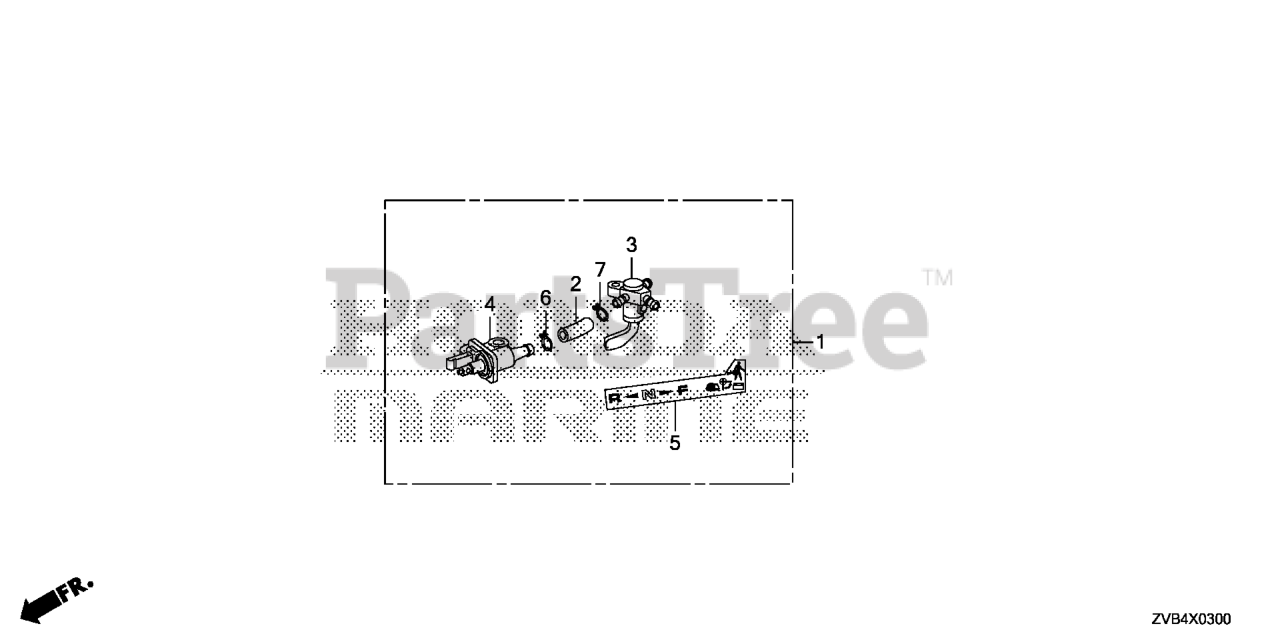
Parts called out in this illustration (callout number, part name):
1	CONNECTOR KIT, FUEL (US)
2	TUBE B, FUEL
3	PETCOCK ASSY. (THREE-WAY)
4	CONNECTOR ASSY., FUEL (B)
5	MARK, CHANGE FUEL PETCOCK (E)
6	CLIP, TUBE (B1 11)
7	CLIP, TUBE (B1 10)
